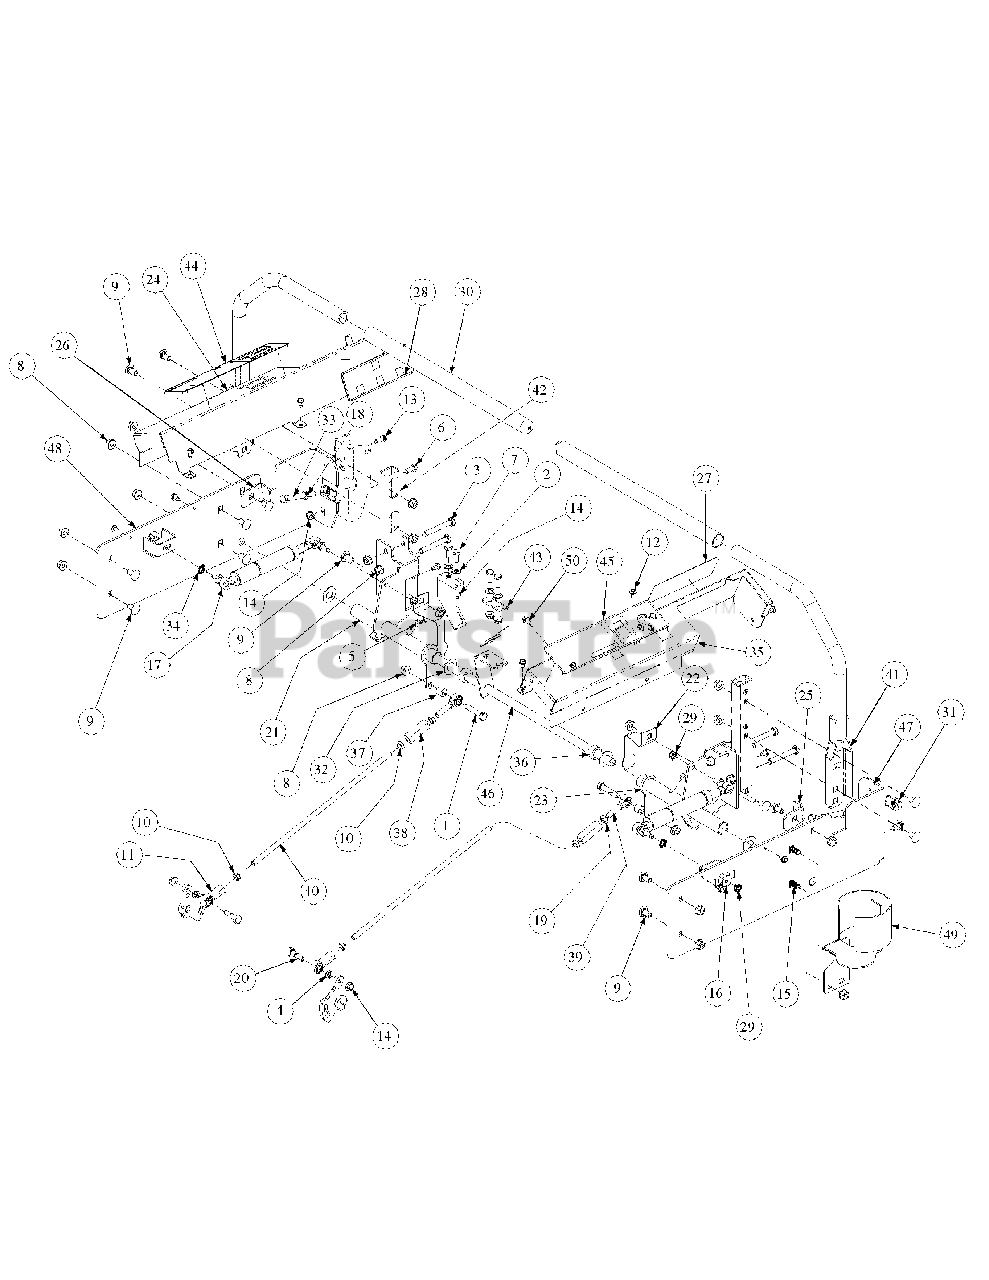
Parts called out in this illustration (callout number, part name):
1	Capscrew, 3/8-16 x 1-3/4
2	Flat Washer, 5/16
3	HHCS, 3/8-16, 2.25
4	5/16, Lock Washer
5	Grease Fitting, 90°.
6	HHCS, 5/16-18 x 1.0
7	Hex, Cap Screw, 5/16-18 x 3/4
8	Hex Nut, 3/8-16, Lock Flange
9	Carriage Bolt, 3/8-16 x .75
10	Hex Jam Nut, 3/8-24
11	B/Joint, 3/8-24, Right Hand Female
12	Screw, TT, 1/4-20, 0.5, Hex Index Washer
13	Screw, TT, 1/4-20, 0.75, Hex Index Washer
14	Nut, Lock, Hex Flange, 5/16-18
15	Carriage Bolt, 3/8-16 x 1
16	Belle Washer, .325 x .930 x .045
17	Cylinder Return to Neutral
18	Nut, 3/8-16, Jam
19	Nut, 3/8-24, Jam, LH Third
20	Screw, Shoulder Control Rod
21	Hub Assy, Control LH Bearing
22	Lever, Safety Switch
23	Hub Assy, Control RH Bearing
24	Control Panel, LH
27	Decal Right Hand Control
28	Decal, Left Hand Control
29	Nut, Hex, Center Lock, M8
30	Grip, 1.0
31	U-Nut, 3/8-16, .75
32	Flat Washer, 5/8 Nylon
33	HHCS, 3/8-16, 3.00
34	External Washer, 3/8
35	Control Panel, RH
36	Shaft Collar
37	Spacer, .385ID x .625 OD x .50 Lg
38	Turnbuckle
39	B/Joint, 3/8-24, Left Hand Female
40	Rod Connector 3/8 OD x 14.25
41	Lapbar, Handle Assembly
42	Mounting Handle
43	Switch Mounting Bracket, Lapbar
44	Decal, Left Hand Console
45	Decal , Right Hand Console
46	Shaft Control Brake Steering
47	Side Panel, Control, Right
48	Side Panel, Control, Left
49	Cup Holder Assembly
50	Screw Button Head, 1/4-20 x .5
